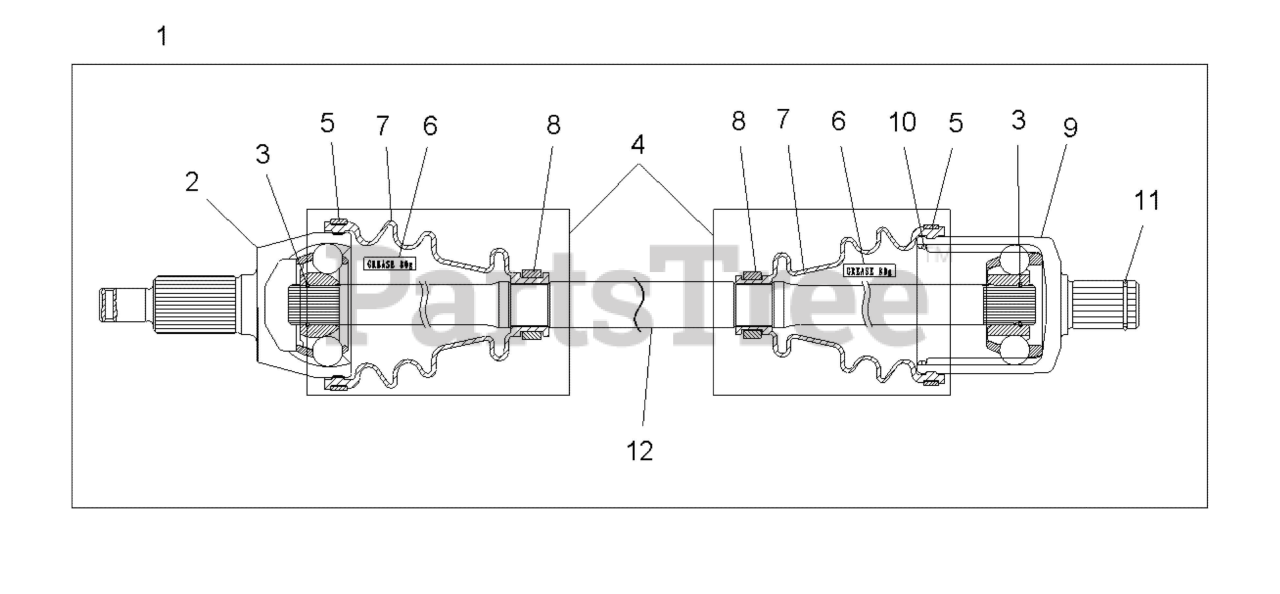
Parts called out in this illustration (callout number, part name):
1	ASM-HALF SHAFT,FRONT,LT
2	JOINT-CV,OUTER
3	CIRCLIP-1.8X22.2(PR-3011)
4	KIT-BOOT,PLUNGING JNT(PR-8062)
5	CLAMP-LARGE(PR-2019)
6	GREASE(K575/VW738)
7	BOOT(PR-0015)
8	CLAMP-SMALL(PR-0016)
9	JOINT-CV,INNER
10	CIRCLIP-2.0X61.7(PR-2016)
11	CIRCLIP-1.6X24.4(PR-2025)
12	SHAFT,23.5(PR-315)
